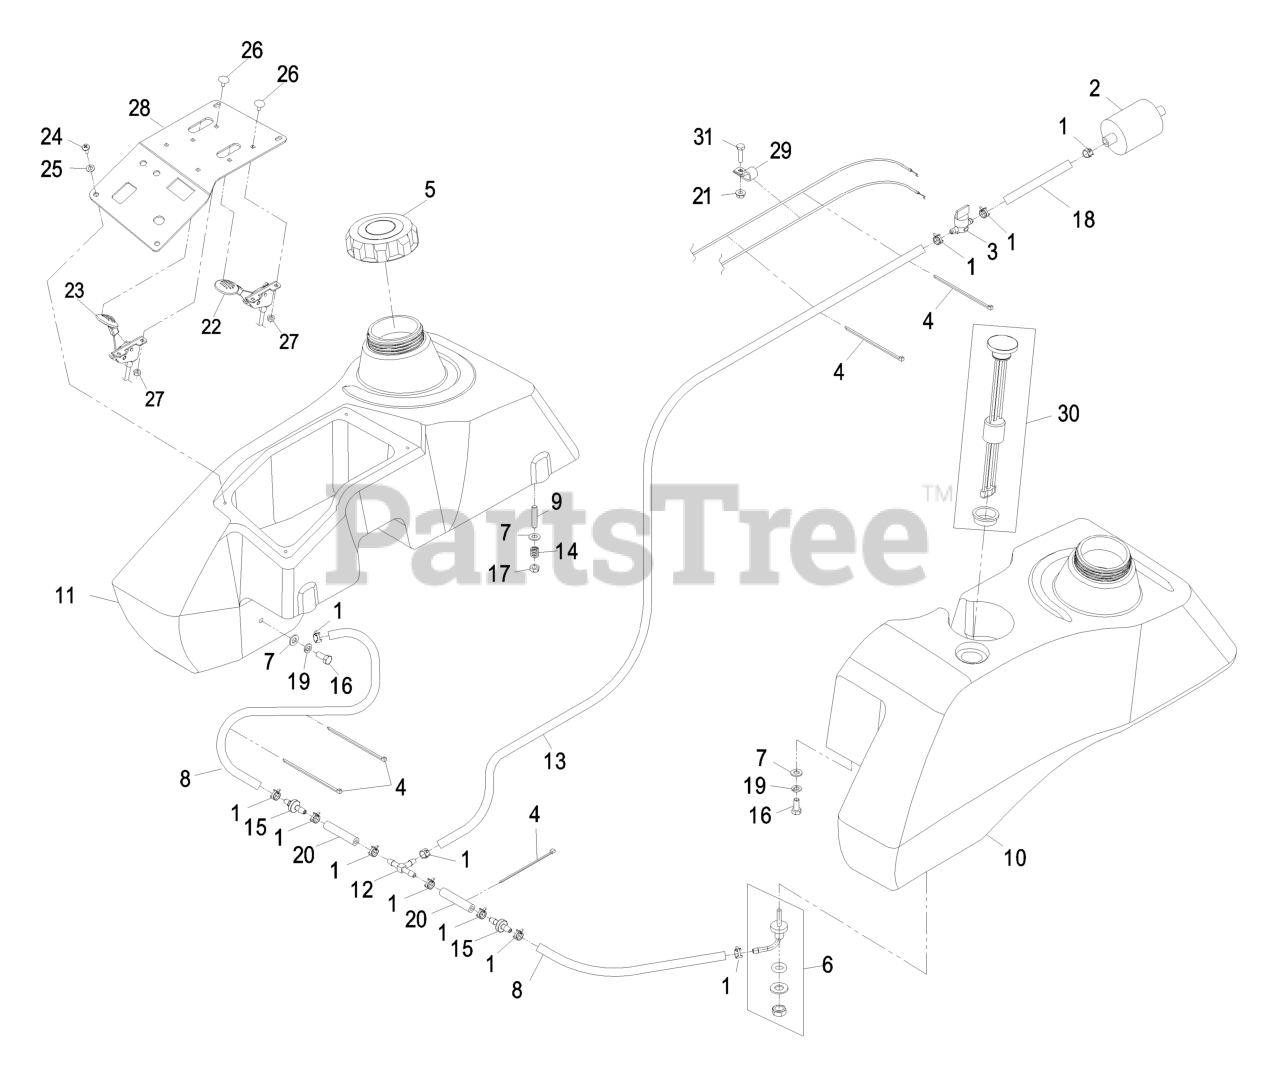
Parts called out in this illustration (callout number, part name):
2	Kohler Part No. 2405010 Fuel Filter
3	VALVE-FUEL
4	TIE-PLASTIC
5	CAP-FUEL, GAS
6	FITTING-FUEL, BULKHEAD
7	WASHER-PLAIN
8	HOSE-FUEL
9	STUD
10	ASM,FUEL TANK LH
12	FITTING-TEE, BARBED
13	HOSE-FUEL
14	SPRING-TANK, FUEL
15	VALVE-CHECK, FUEL
16	SCREW-HH
17	NUT-LOCK, NI
18	HOSE-FUEL
19	WASHER-LOCK
20	HOSE-FUEL
22	CONTROL-THROTTLE
23	CONTROL,CHOKE
24	SCREW-PTH
25	WASHER-SPRING
26	BOLT-CARR
27	NUT-LOCK, NI
28	PANEL,CONTROL W/DECALS
29	CLIP-LOOM
30	Kit, Gauge Fuel
31	SCREW-HH
